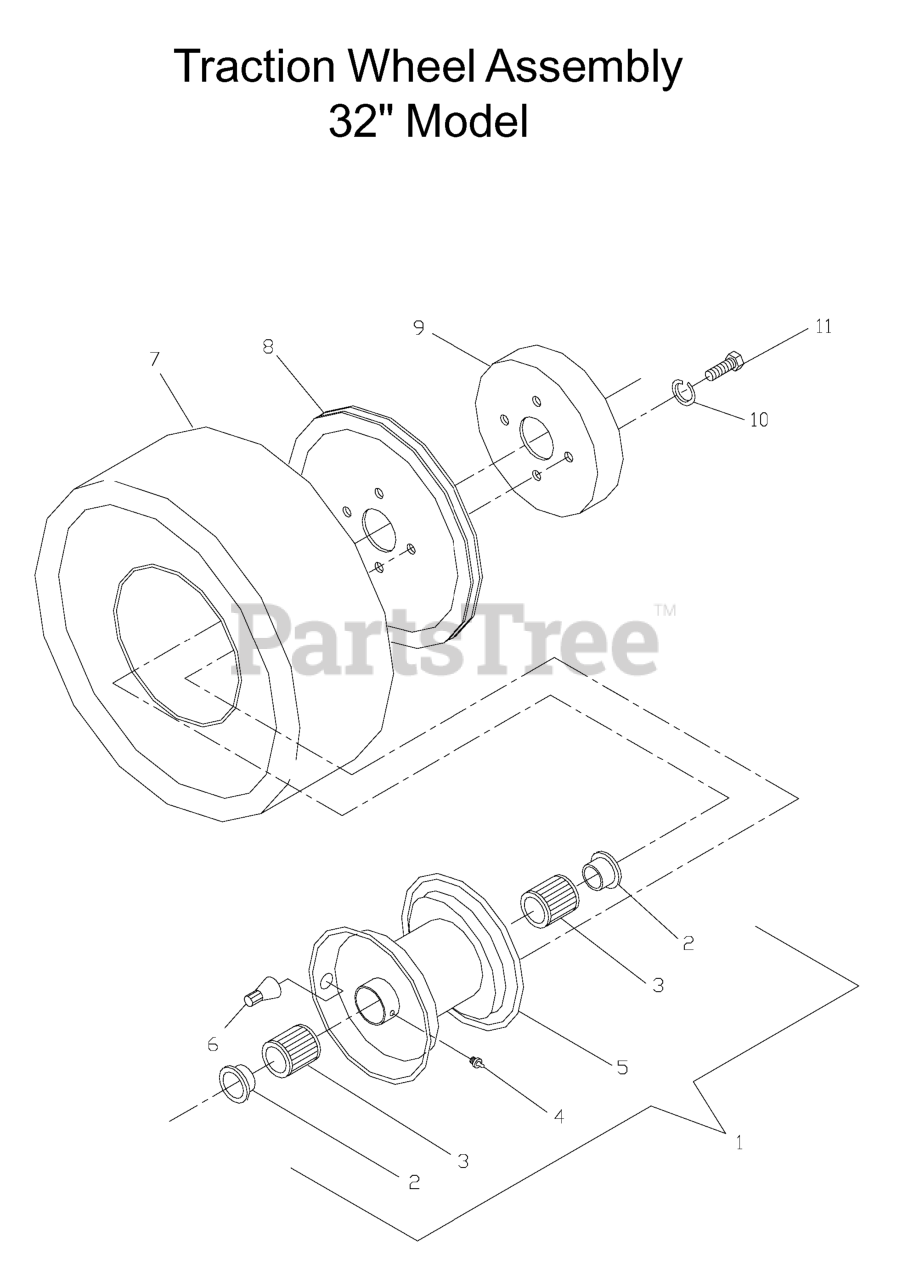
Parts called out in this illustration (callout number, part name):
2	BEARING FLANGE
3	ROLLER BEARING (LONG)
4	ZERK
6	VALVE STEM TR-412
8	TRACTION PULLEY
9	BRAKE DRUM
10	SLW 3/8 STD
11	HCS 3/8F X 3/4
